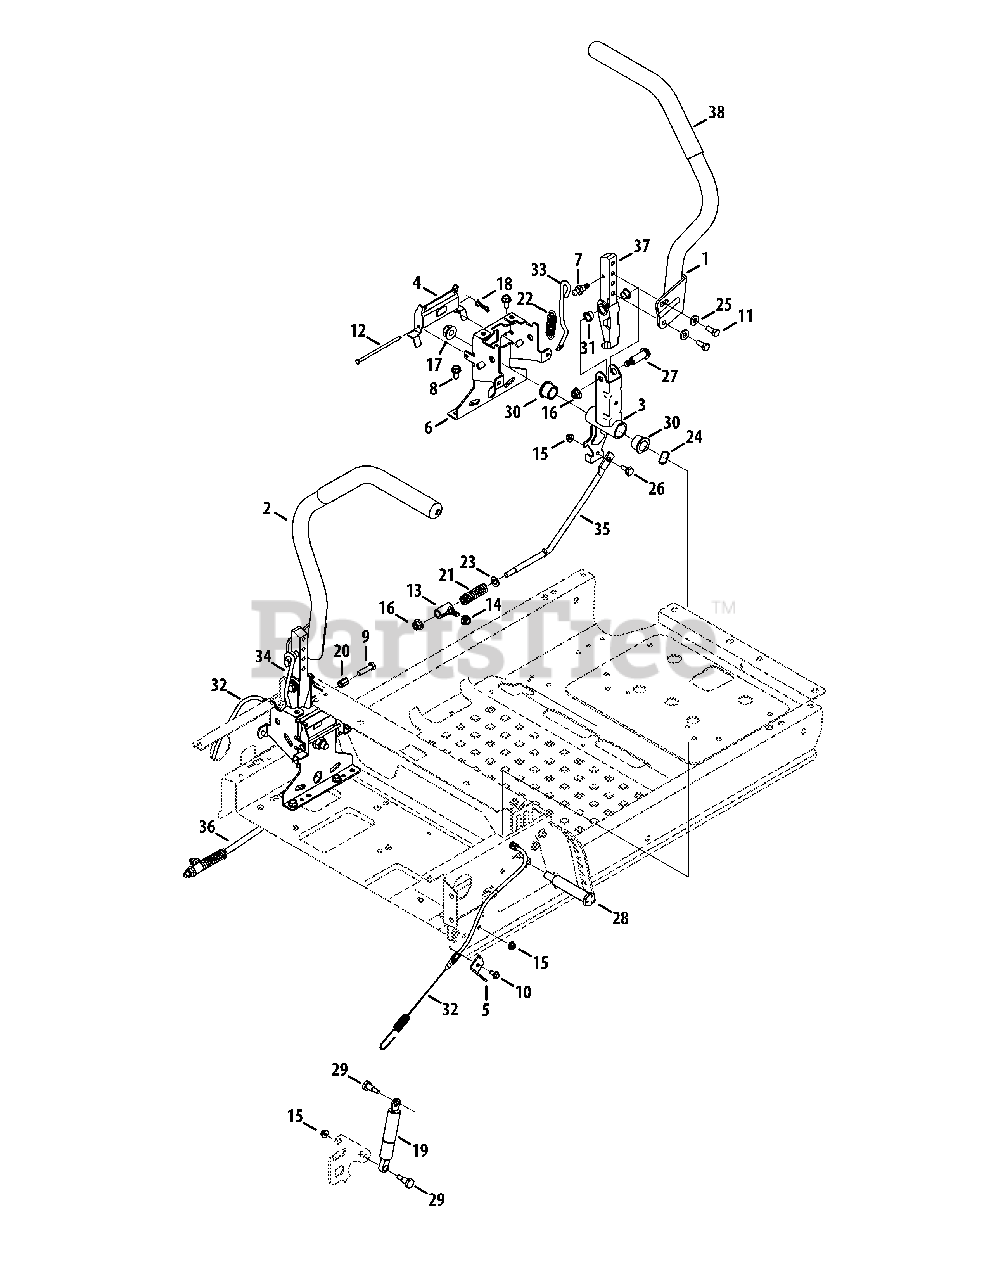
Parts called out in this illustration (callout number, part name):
1	RH Lapbar Lever Assembly
2	LH Labpar Lever Assembly
3	Lapbar Pivot Bracket
4	Brake Lever Actuator
5	Brake Cable Bracket
6	Lapbar Pivot Support Bracket
7	Shoulder Ball Screw 5/16-18 x .48
8	Hex Washer Screw 5/16-18 x .750
9	Hex Cap Screw 5/16-18 x 1.25
10	Hex Washer Screw 1/4-20 x .500
11	Hex Head Screw 5/16-18 x .75, Patch
12	Pin .188 x 4.1
13	Ferrule, 3/8 ID x .420 Shldr
14	Flange Lock Nut 5/16-18
15	Flange Lock Nut 1/4-20
16	Flange Lock Nut 3/8-16
17	Flange Lock Nut 1/2-13
18	Bow-Tie Cotter Pin
19	Dampener .87 OD x 7.06 Lg
20	Nut 5/16-18
21	Compression Spring .45 x 3.215
22	Extension Spring .56 x 2.31 x .105
23	Flat Washer .385 x .62 x .063
24	Washer, Wave .785 x 1.0 x .012
25	Flat Washer .344 x .750 x .120
26	Shoulder Screw .375 x .148 x 1/4-20
27	Shoulder Screw .498 Dia. x 1.296
28	Shoulder Screw .75 x 3.25 x 1/2-13
29	Shoulder Screw .395 Dia. x .56
30	Bearing .75 x 1.00 x .73
31	Flange Bearing .500 x .34
32	Parking Brake Cable
33	Lapbar Detent Rod, RH
34	Lapbar Detent Rod, LH
35	Hydro Control Rod, RH
36	Hydro Control Rod, LH
37	Lower Arm
38	Lapbar Grip, Long 1.125 x 12.00 Lg
